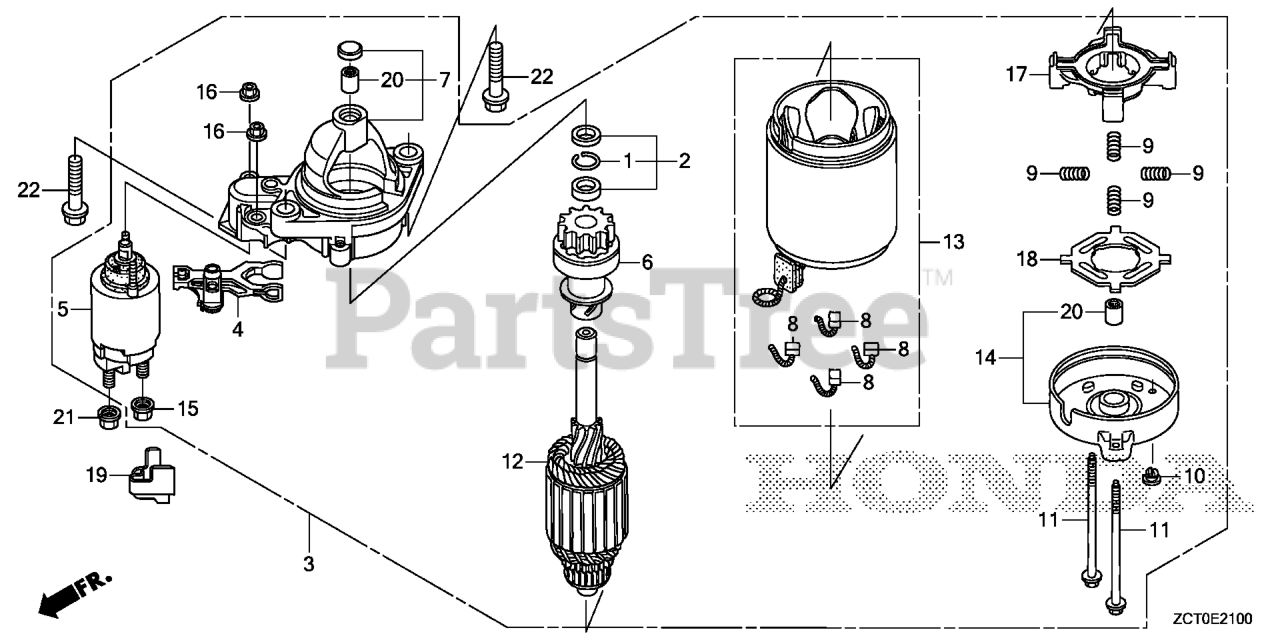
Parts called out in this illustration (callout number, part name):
1	RING, SNAP (DENSO)
2	COLLAR SET, CLUTCH STOP
3	STARTER MOTOR ASSY.
4	LEVER, PINION DRIVE
5	SWITCH ASSY., MAGNET
6	CLUTCH, OVERRUNNING
7	HOUSING, DRIVE SIDE
8	BRUSH
9	SPRING, BRUSH
11	BOLT, THROUGH
13	YOKE
14	FRAME, COMMUTATOR END
15	NUT, HEX. (8MM)
16	NUT, FLANGE (5MM)
17	HOLDER, BRUSH
18	INSULATOR, BRUSH HOLDER
19	COVER, TERMINAL
20	BEARING A
21	NUT-WASHER (8MM)
22	BOLT, FLANGE (10X40)
